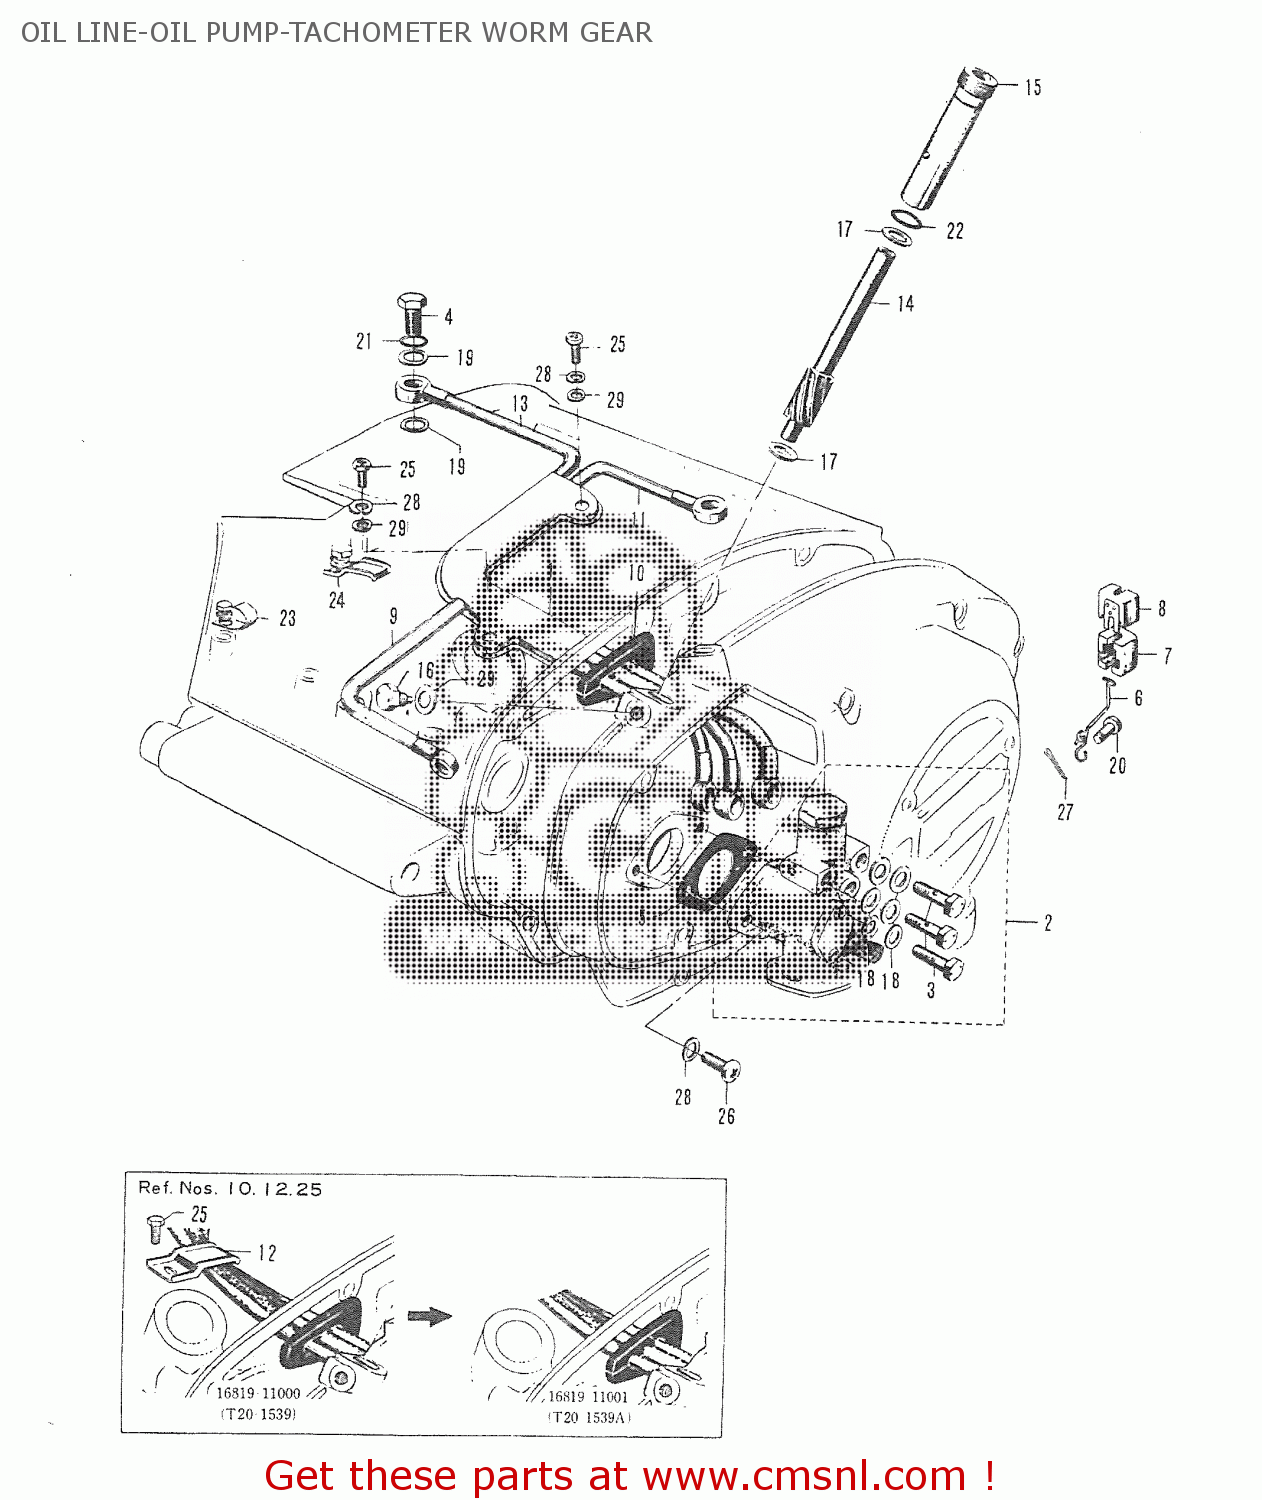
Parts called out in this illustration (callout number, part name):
1	OIL LINE COVER
2	OIL PUMP ASS'Y
3	OIL PUMP UNION BOLT
4	VALVE,CHECK
5	GASKET,OIL PUMP (MCA)
6	OIL PUMP LEVER CHAIN
7	OIL PUMP LEVER CHAIN CONNECTOR
8	OIL PUMP LEVER CHAIN CONNECTOR (TC250TC250)
9	OIL TANK SIDE OIL LINE
10	OIL LINE BUSHING
11	RIGHT CYLINDER SIDE OIL LINE
12	OIL LINE CLIP BAND
13	LEFT CYLINDER SIDE OIL LINE
14	TACHOMETER WORM GEAR
15	TACHOMETER WORM GEAR BUSHING
16	BOLT
17	WASHER(8X13.7X1)
18	GASKET (NAS)
19	GASKET(10X16X3) (NAS)
20	OIL PUMP LEVER PIN
21	O RING(D:1.3,ID:7.6)
22	O RING(D:1.3,ID:9.6)
23	CLAMP
24	OIL LINE CLIP BAND
25	HEXAGON BOLT
26	CROSS HEAD SCREW
27	COTTER PIN
28	LOCK WASHER
29	SMALL FLAT WASHER
